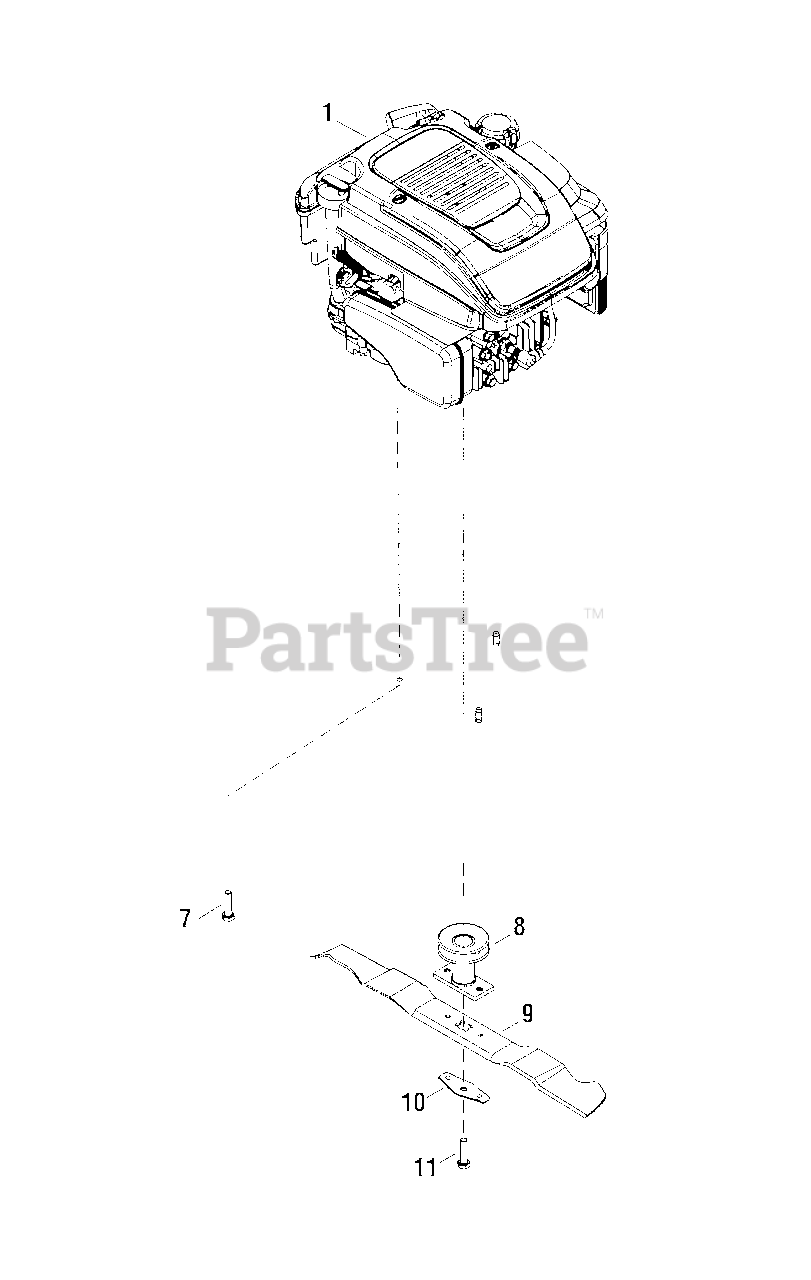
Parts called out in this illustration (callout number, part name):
1	* ENGINE, Briggs & Stratton, Mod. 103M02-0004 -F1
7	SCREW, Engine Mounting, 3/8-16 x 1
8	ASSEMBLY, Blade Adapter
9	BLADE, Mulching
10	SUPPORT, Blade Bell
11	SCREW Hex, 3/8-24 x 1-1/2
